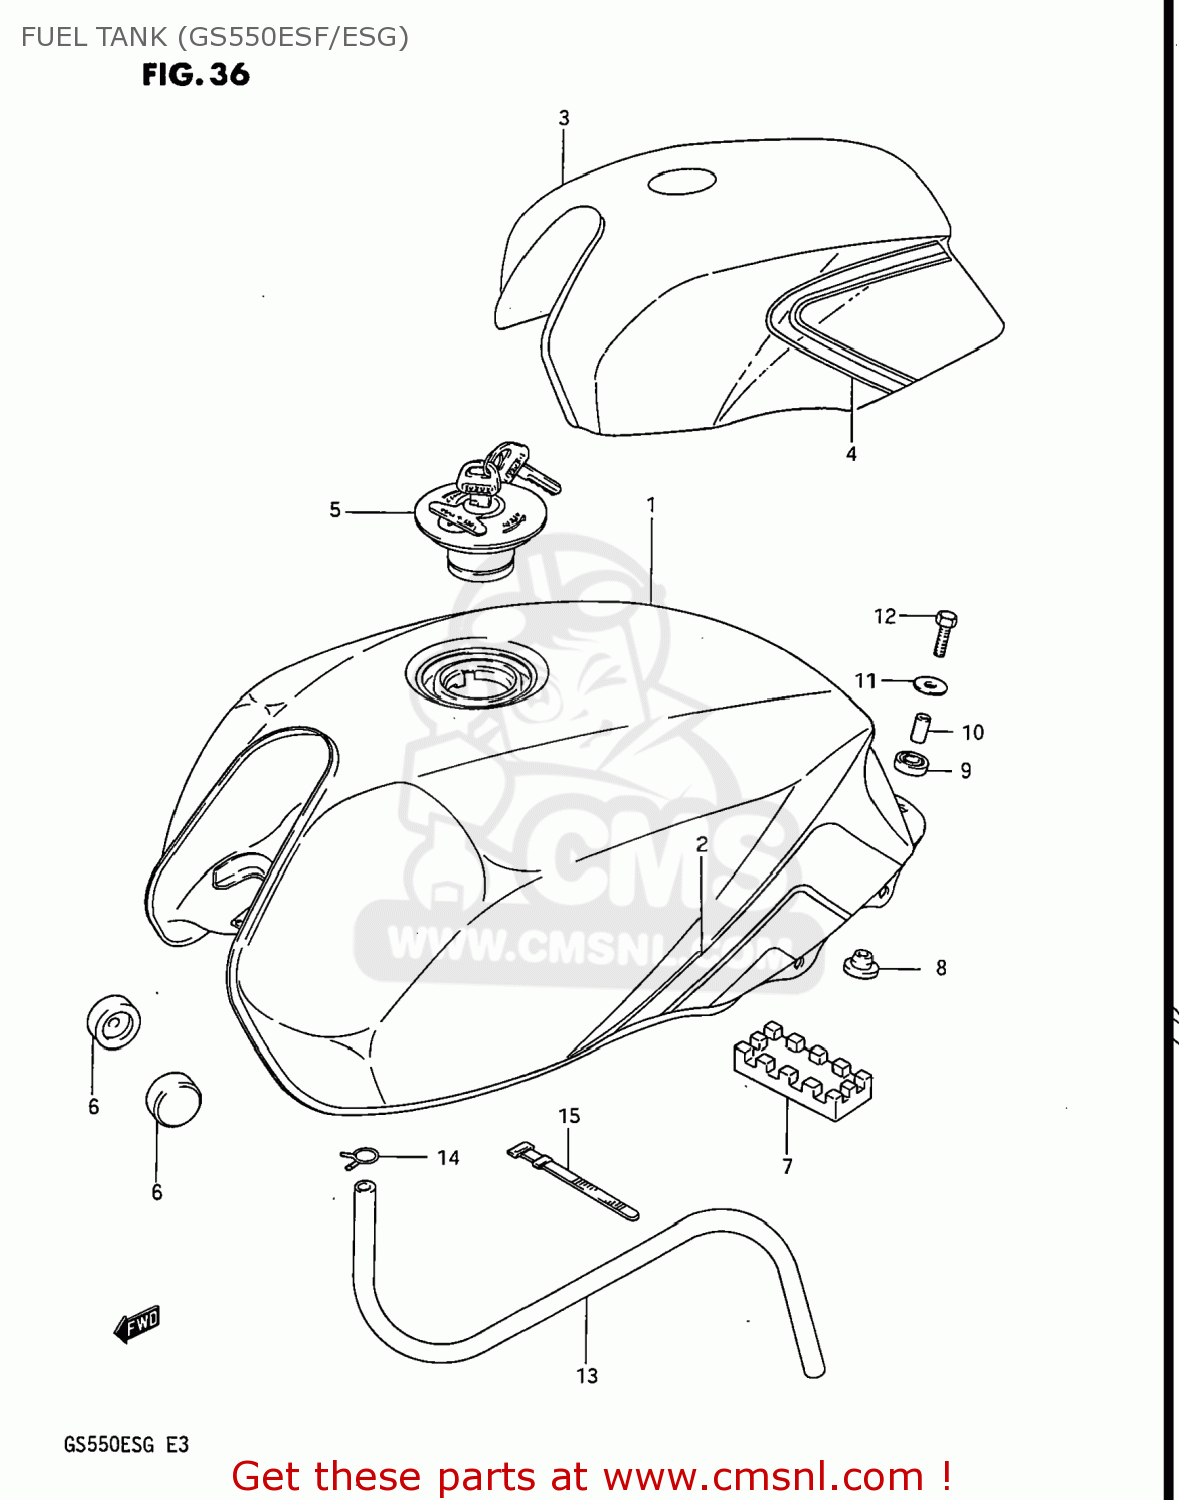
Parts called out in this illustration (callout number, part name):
1	TANK ASSEMBLY,FUEL
2	TAPE SET,FUEL TANK
3	TANK ASSEMBLY,FUEL
4	TAPE SET,FUEL TANK
5	CAP SET,FUEL TANK
6	CUSHION
7	CUSHION,FUEL TANK
8	CUSHION
9	CUSHION
10	SPACER (6.4X9X20)
11	WASHER (6.5X24X1.6)
12	BOLT
13	HOSE,FUEL
14	CLIP
15	CLAMP(L:187)
